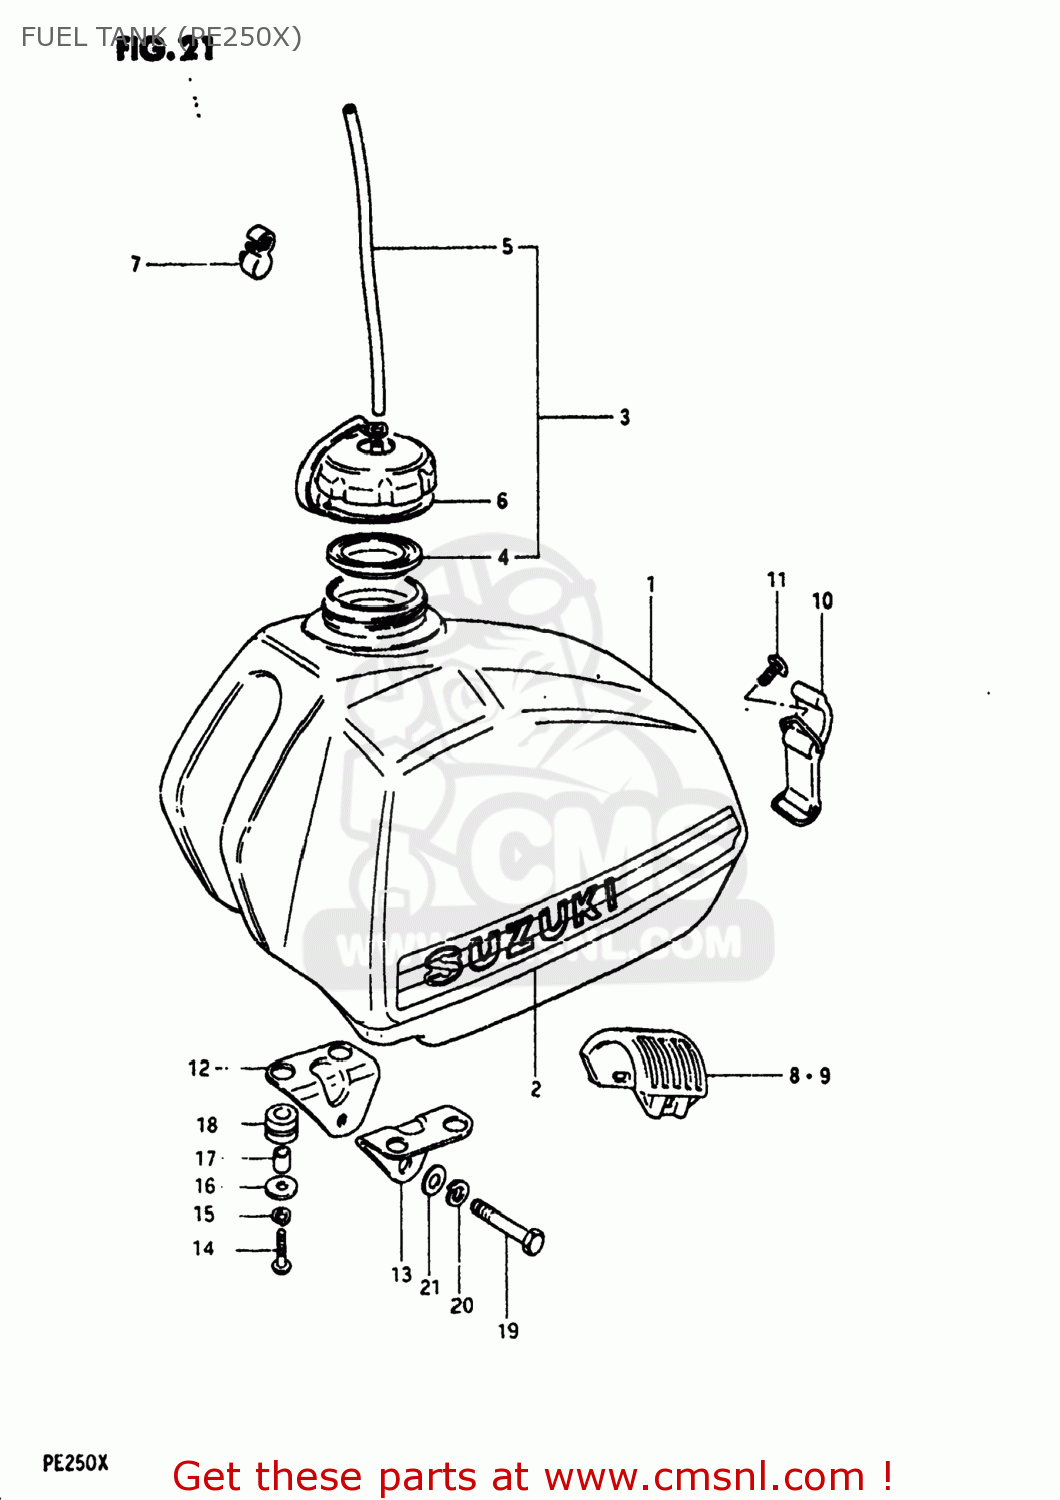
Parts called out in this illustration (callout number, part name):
1	TANK ASSEMBLY,FUEL
2	TAPE SET,FUEL TANK
3	CAP,FUEL TANK
5	HOSE
6	BAND,FUEL TANK CAP
7	CLAMP,BREATHER HOSE
8	CUSHION,FUEL TANK
9	CUSHION,FUEL TANK UPR FR
10	BAND
11	SCREW(6X18)
12	BRACKET,FUEL TANK
13	BRACKET,FUEL TANK,LOWER
14	SCREW
15	LOCK WASHER
16	WASHER (6.5X24X1.6)
17	SPACER(6.8X12X11)
18	CUSHION
19	BOLT
20	LOCK WASHER
21	WASHER
